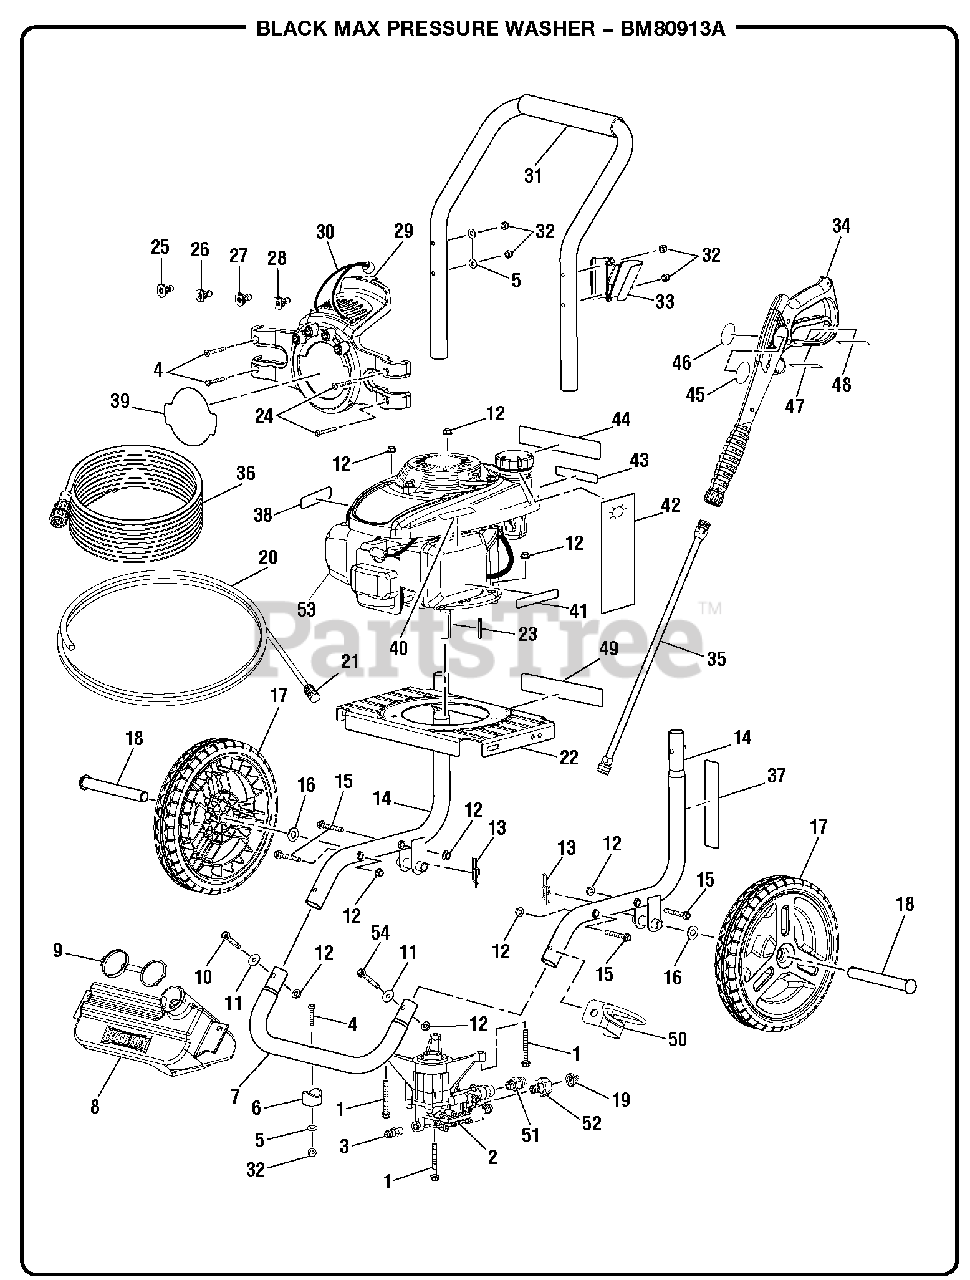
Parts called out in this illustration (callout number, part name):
1	Bolt (M8 x 60 mm, Flange Hd.)
2	Pump
3	Thermal Release Valve
4	Screw (1/4-20 x 1.85 in., T30 Torx Hd.)
5	Washer (1/4 in.)
7	Front Frame
8	Soap Tank
9	Soap Tank Cap
10	Bolt (M8 x 45 mm)
11	Washer (5/16 in.)
12	Hex Nut (M8 x 1-1/4 in.)
13	Ring Clip
14	Main Frame Assembly
15	Bolt w/Washer (M8 x 55 mm, Hex Hd.)
16	Washer (1/2 in.)
19	Filter Screen (Pump Inlet)
20	Chemical Siphon Tube
21	Chemical Siphon Filter
22	Engine Plate
23	Output Shaft Key (3/16 in. x 40 mm)
24	Screw (1/4-20 x 2.27 in., T30 Torx Hd.)
25	40deg Nozzle
26	Soap Nozzle
27	25deg Nozzle
28	0deg Nozzle
29	Hose and Nozzle Holder Assembly
30	Bungee Cord and Bead Assembly
31	Handle w/Foam
32	Lock Nut (1/4-20)
33	Wand Holder
34	Trigger Handle Assembly
35	Extension Wand
36	Hose (25 ft., 3000 psi)
37	Label (Pump Quick Start)
38	Label (Hot Muffler)
39	Label (Performance)
40	Label (Inquires)
41	Label (Engine Quick Start)
42	Label (Oil Hang Tag)
43	Label (UL Fire Warning)
44	Label (Warning)
45	Label (Wand Warning)
46	Label (Wand Logo)
47	Label (Warning)
48	Label (Wand Rating)
49	Data Label
50	Wand Holder
51	Outlet Tube
52	Inlet Tube
53	Engine
54	Bolt (M8 x 50 mm, Flange Hd.)
